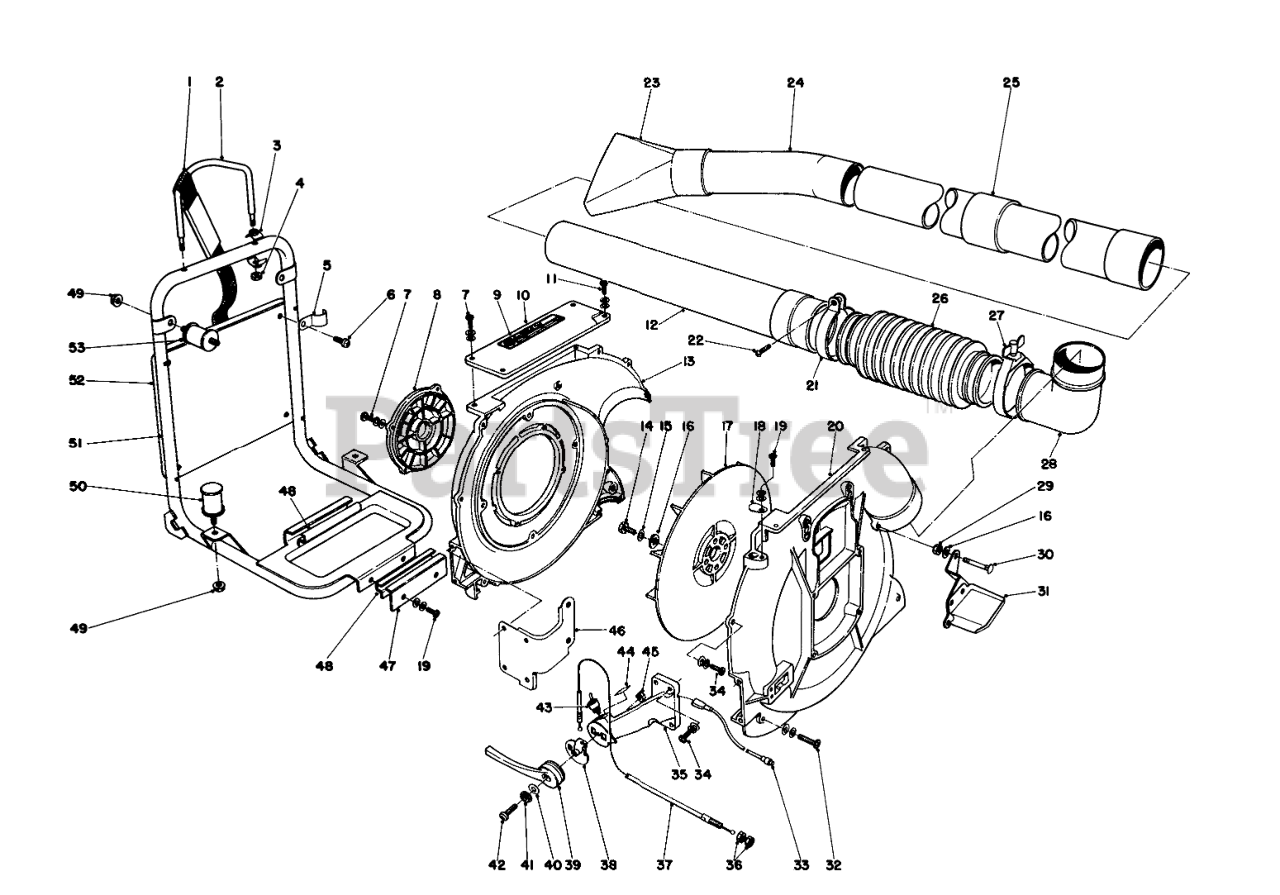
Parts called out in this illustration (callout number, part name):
1	Shoulder Strap
3	Adapter
4	Locknut
5	Bracket Cushion
6	SCREW-SHWH
7	Screw
8	Grid, Fan Case
9	Decal-Warning
10	Plate
11	Screw
12	STRAIGHT PIPE/SWIVEL
13	Fan Case, Operator Side
15	Washer
16	WASHER
19	SCREW
20	Fan Case, Starter Side
21	Clamp
22	Screw
23	FAN HD NOZZLE
24	CURVED PIPE
25	Straight Pipe
26	FLEXIBLE PIPE
27	CLAMP
28	Elbow
29	Capnut
30	Bolt, Elbow
31	Bracket, Muffler Cover
33	Lead Switch
34	Screw
35	THROTTLE LEVER BRKT
37	THROTTLE CABLE
39	THROTTLE LEVER
40	Washer
41	Washer
42	Screw
43	SWITCH
44	STOP SWITCH DECAL
46	Bracket
47	Bracket-Fuel Tank
48	Cushion-Fuel Tank
50	Cushion
51	Frame, Back Pack
52	Back Pack Pad
53	Cushion
